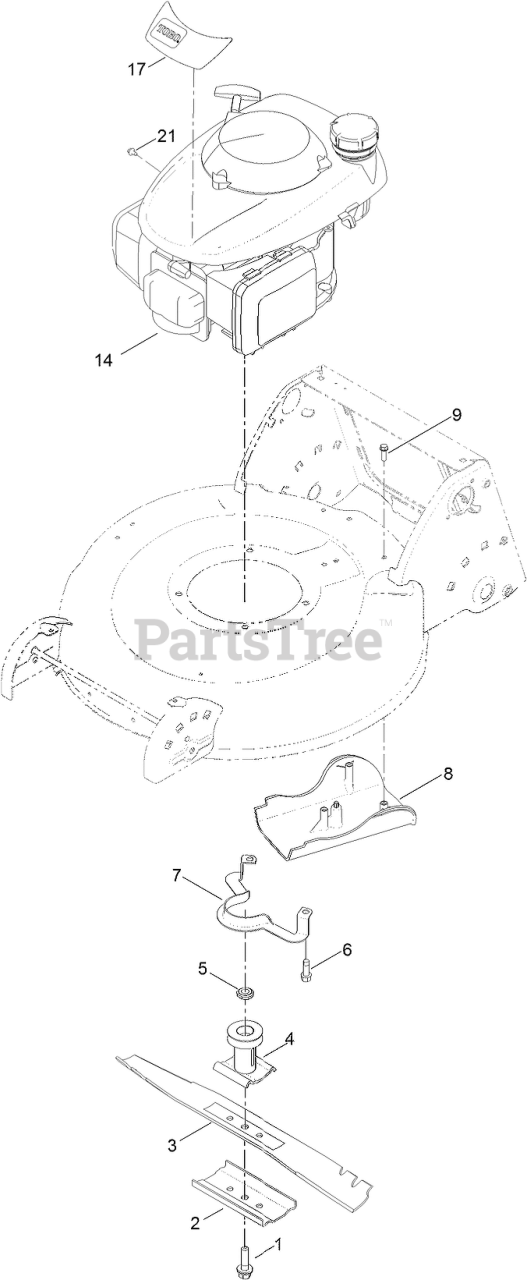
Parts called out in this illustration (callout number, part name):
1	BOLT-BLADE
2	SUPPORT-BLADE
3	BLADE-21 INCH
4	DRIVER-BLADE
5	Spacer-Driver
6	SCREW-TAPTITE
7	Guide-Belt
8	COVER-BELT
9	SCREW-HWH
14	ENGINE-HONDA,GCV160A0-S3TE GAS
17	DECAL-ENGINE
21	SCREW-HWH
